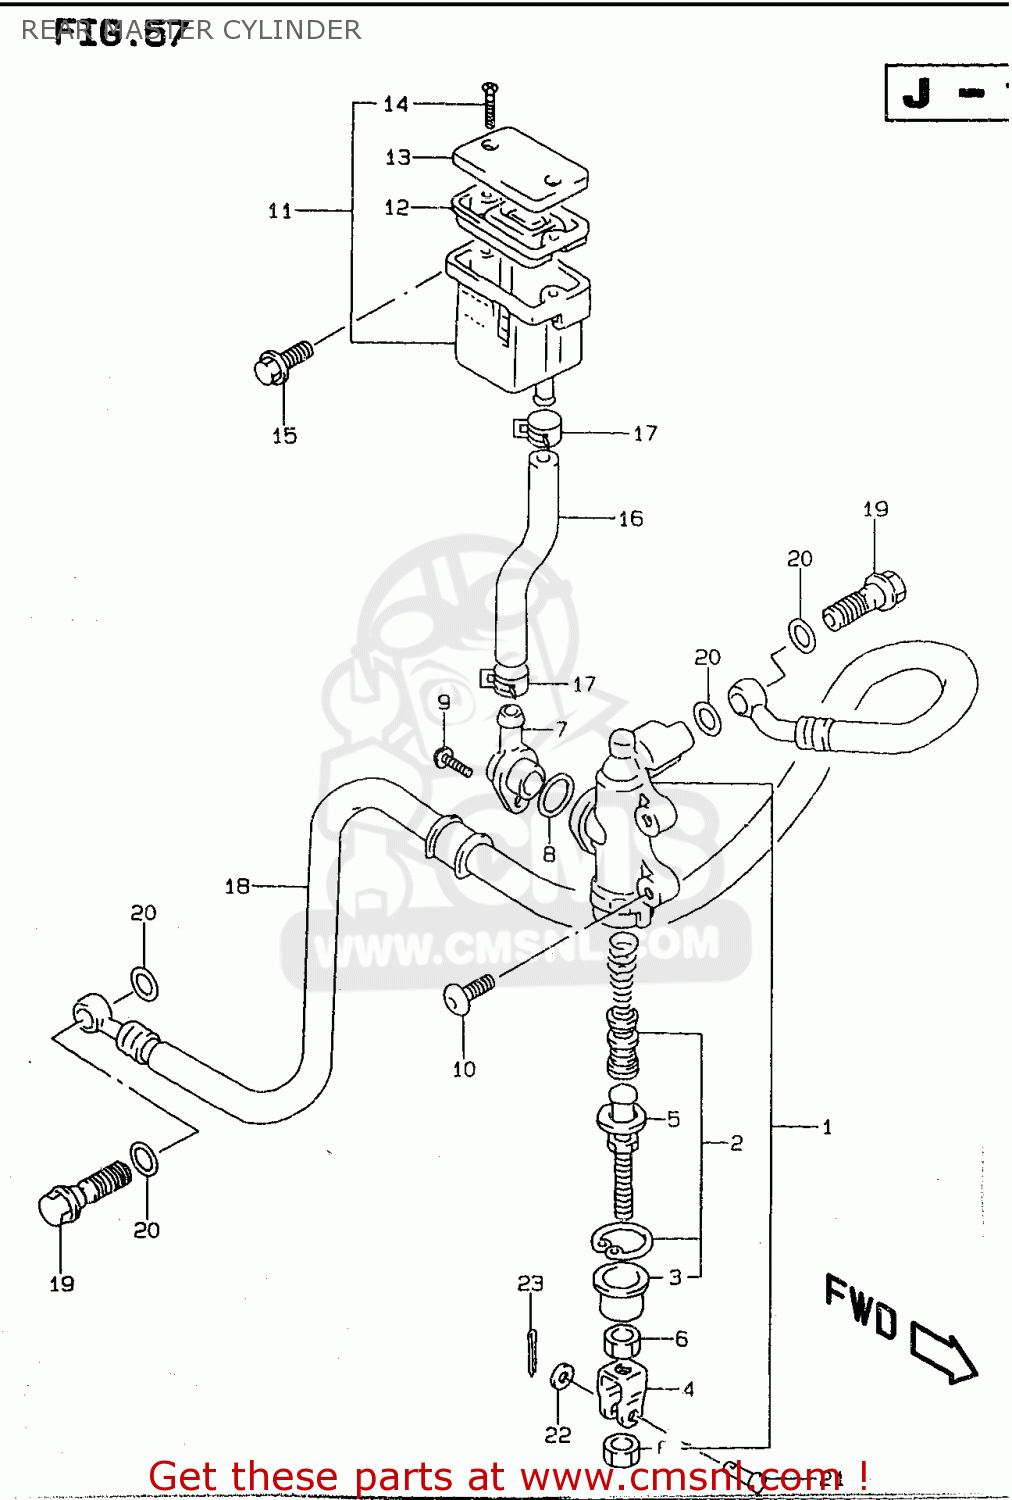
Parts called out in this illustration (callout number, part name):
1	CYLINDER ASSY,RR MASTER
2	PISTON/CUP SET
3	BOOT
4	YOKE
5	ROD,PUSH
6	NUT
7	CONNECTOR
8	O RING
9	SCREW
10	BOLT 8X20
11	TANK ASSY,RESERVOIR
12	DIAPHRAGM
13	CAP
14	SCREW
15	BOLT
16	HOSE,RESERVOIR TANK
17	CLIP
18	HOSE,RR BRAKE
19	BOLT UNION
20	WASHER(10X15X1.5)
21	PIN
22	WASHER
23	PIN
